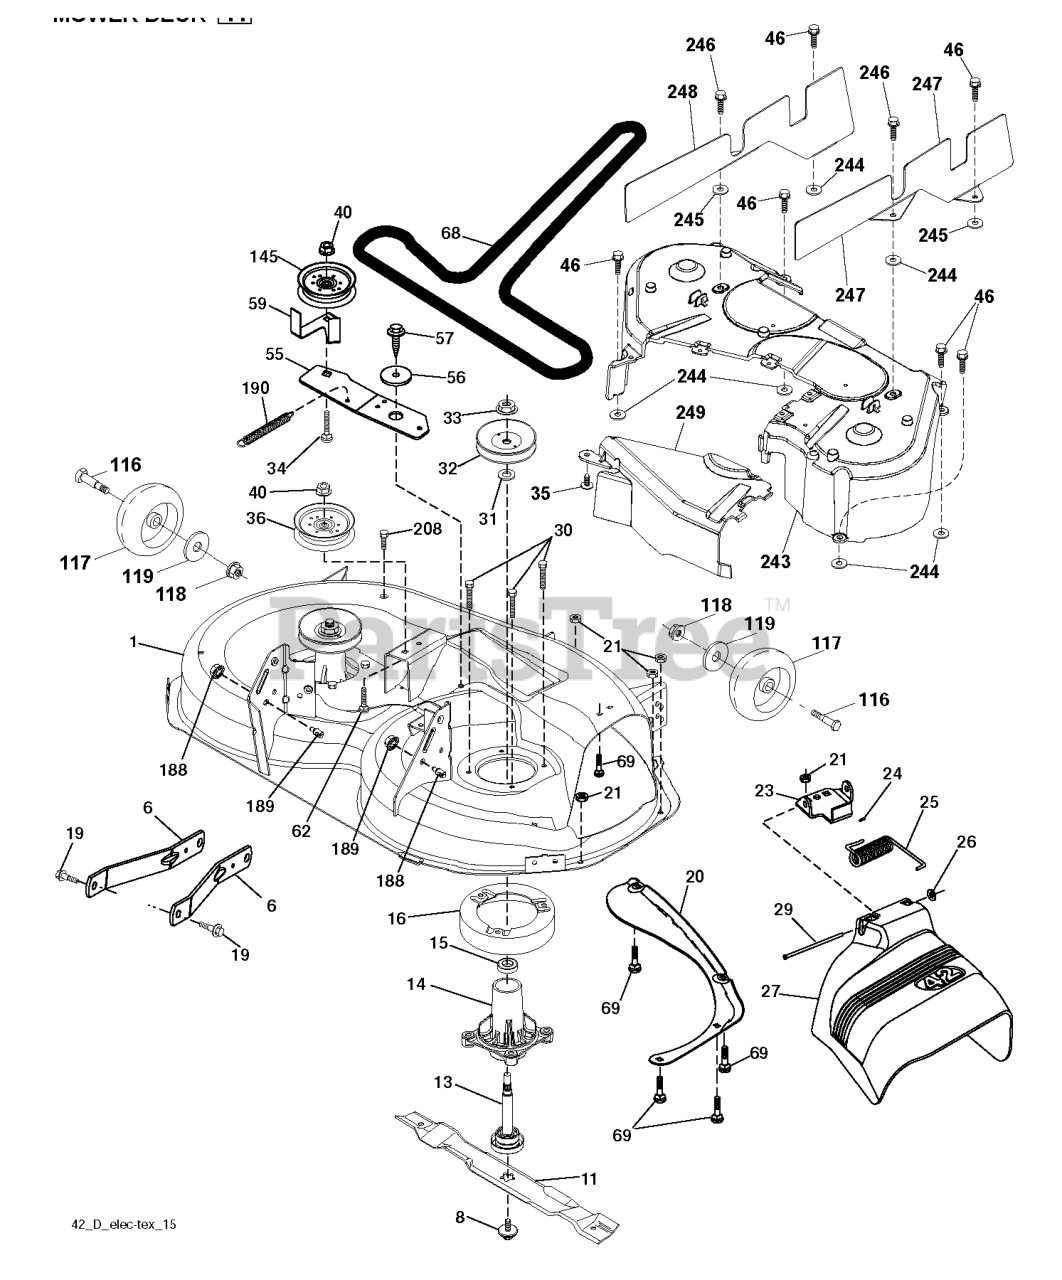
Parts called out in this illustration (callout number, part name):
1	DECK.WELDMENT.42"
6	ARM.SUSPENSION.MOWER.R
8	BOLT.WASHER.ASM.7/16-2
11	42" HI-LIFT BLADE
13	SHAFT.ASM.MDRL.N/GREASE.38
14	RP.HOUSING.MANDREL.4PT.
16	STRIPPER.MANDREL.ROUND.BLACK
19	BOLT.SHOULDER
20	BAFFLE.VORTEX
21	LOCKNUT
23	BRKT.DEFLECTOR.38"2005+
24	CAP-SLEEVE LT
25	SPRING.TORSION.DEFLECT
26	NUT PUSH M
27	DEFLECTOR ASM.42"TEX.FRENCH
29	ROD.HINGE
30	SCREW, WASHER HEAD
31	WASHER.SPACER.MANDREL
32	PULLEY/MANDREL
33	NUT.FLANGE.LOCK.TOP
34	BOLT.3/8-16X1.50
35	FASTENER.XMAS.TREE
36	PULLEY.IDLER.2006
40	NUT LOCK FLG 3/8-16 UNC
46	SCREW.1/4-20X5/8
56	SPACER.RETAINER
57	SCREW 3/8-16X1
59	GUARD, BELT
68	BELT V SECONDARY
69	BOLT
116	BOLT M
117	WHEEL.GAGE.HALF.SPOKED
118	LOCKNUT
119	WASHER.5/16.FLAT.STE.STD.
145	PULLEY.IDLER.48"PRIMARY
188	STUD.FASTNER.W/ANTI-ROTATE
189	NUT LOCK HEX FLANGE 5/16-18
190	SPRING.MOWER.DRIVE.ELECTRIC
208	SCREW 3/8-16X1/2
244	PALNUT 1/4
245	WASHER 5/16"
246	SCREW, 5/16-18 X 1/2
249	COVER CABLE CLUTCH
